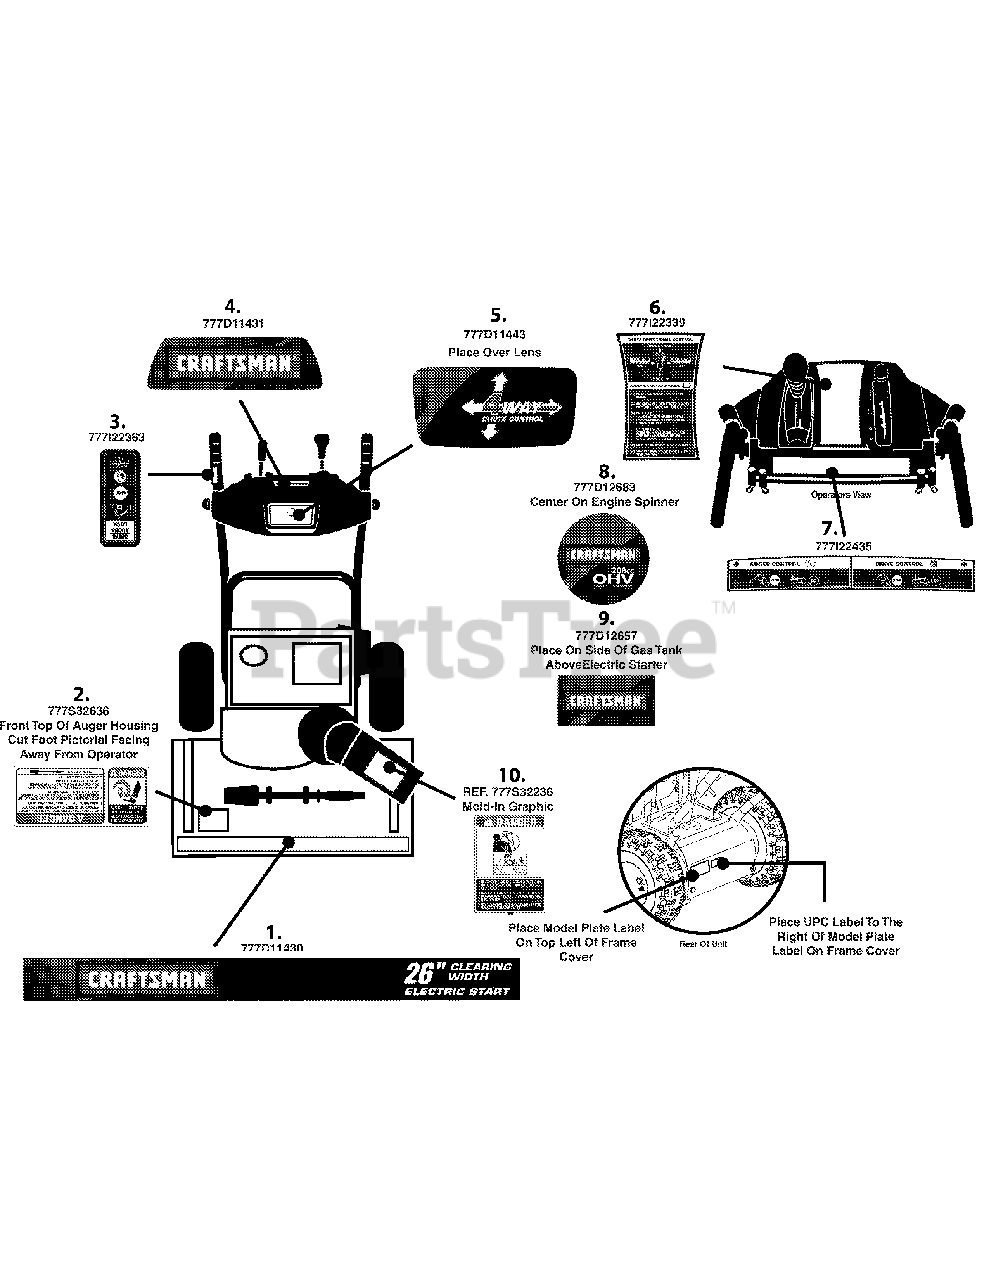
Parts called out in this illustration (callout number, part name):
1	LABEL-SNOW HOUSING CRAFTSMAN 7/26
2	LABEL-SNOW HOUSING
4	LABEL-SNOW PANEL CRAFTSMAN
5	LABEL-SNOW HNDL PANEL 4 WAY
7	LABEL-AUG/DRV CNTRL
8	LABEL:SNW:MTD ENG:CRFTSMN 208CC
9	LABEL:ENG:BTM GAS TANKCRAFTSMAN
10	LABEL:SNOW CHUTE
